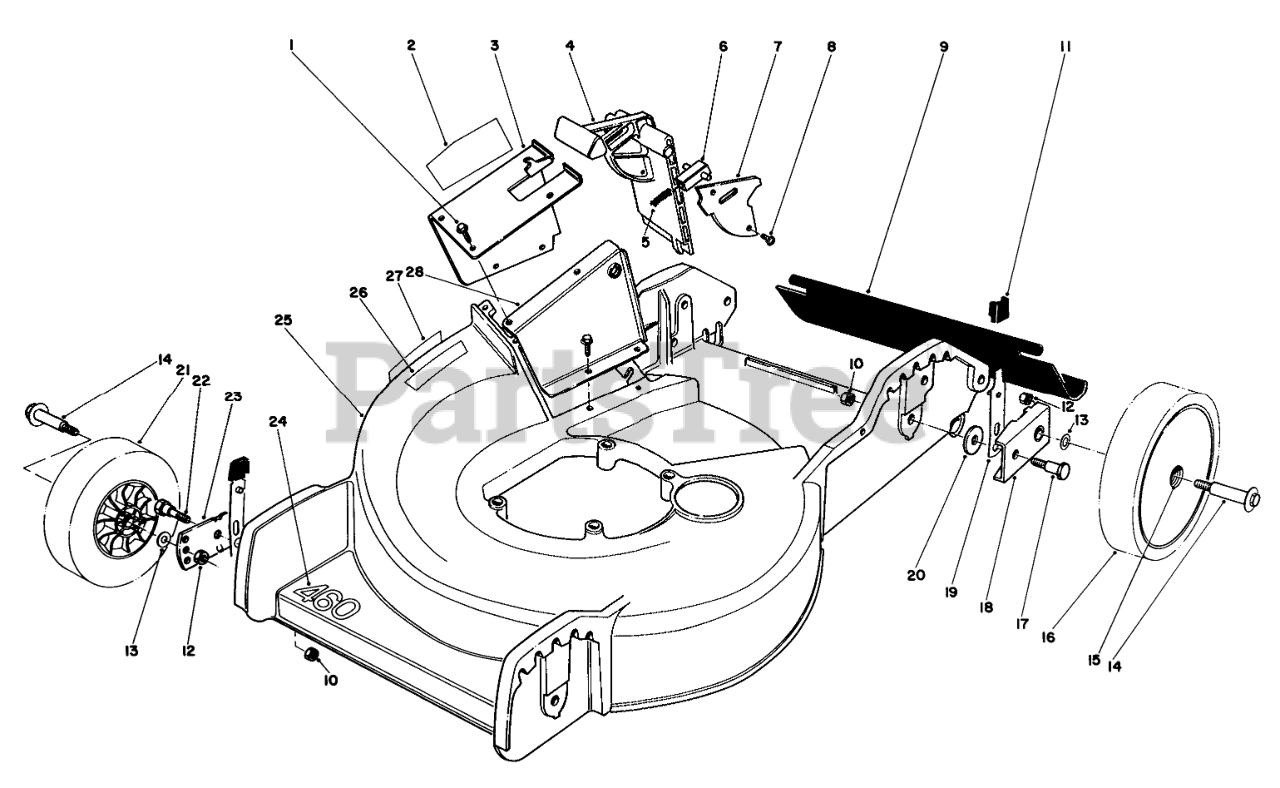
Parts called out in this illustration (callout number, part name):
1	SCREW
2	Decal-Danger
3	Tunnel-Outer (Incl. Ref. #2)
4	Door Mulching
5	SPRING-COMPRESSION, LATCH
6	Door Latch
7	Cover Door
9	SHIELD - TRAILING
10	NUT-LOCK, NI
11	KNOB-ARM
12	Nut
13	WASHER
14	BOLT-WHEEL
15	BUSHING
16	Wheel & Tire Assembly (Incl.Ref. #15)
17	PIVOT SCREW
18	HP PIVOT ARM ASM
19	SPRING ARM ASM
20	PIVOT WASHER
21	Wheel & Tire Assembly (Incl.Ref. #15)
22	PIVOT SCREW
23	PIVOT ARM ASSY
24	Decal-460
25	Housing
26	Decal-Place Foot Here
27	STEP PAD DECAL
28	Inner Tunnel
